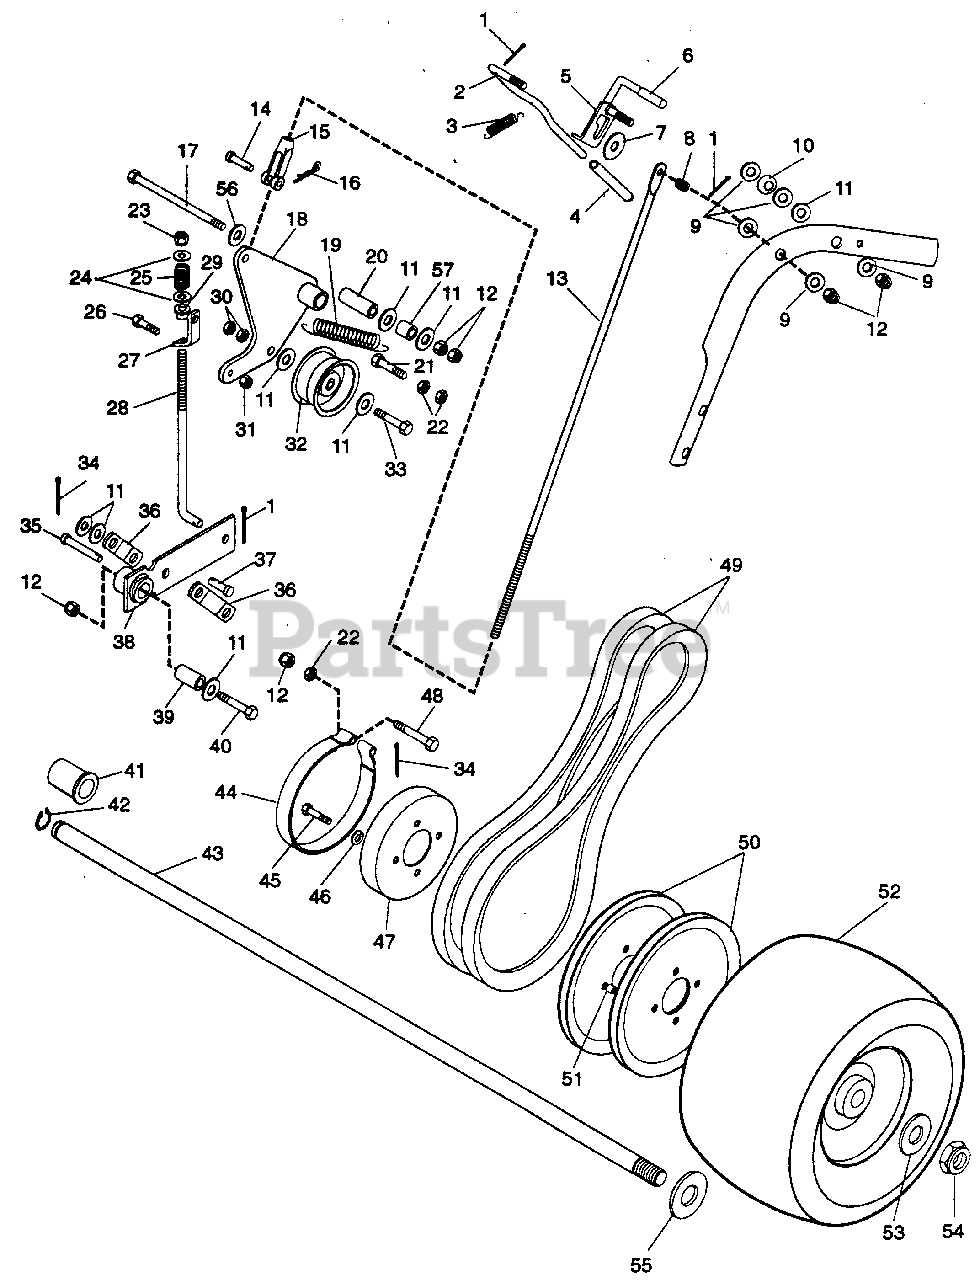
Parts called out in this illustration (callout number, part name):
1	PIN-COTR .09 X .75 PL
2	LVR, HAND CONTROL
3	WLDMT, MWR FRM MULTI-MODE
4	GRIP, HAND CLUTCH LEVER
5	WLDMT, CLUTCH-BRAKE LOCK
6	TIP-BRAKE LOCK LEVER
7	WSHR-FL-STL .438 X 1.375 X .083
8	SG-COMP .045 X .600 X .750 WLD 25
9	WSHR-FL-NY .375 X .75 X .060
10	SPRING WASHER
11	WSHR-FL-STL .406 X .812 X .065 PL
12	NUT-LK-NYL .375-16 PL
13	ROD, CLUTCH ACTUATING
14	PIN-CLEV .372 X 1.25
15	CLVS, 3/8-24 ADJUSTABLE
16	PIN-HAIR INT .08 X .18 X .18
17	BLT-HEX .38-16 X 4.00
18	WLDMT, WHL CLUTCH ARM
19	SG-TENS .069 X .62 X 3.50 WLD 20
20	BUSH., S .385 X .610 X 1.80 ST
21	BLT-HEX .38-16 X 1.50 PL GR 5
22	NUT-HEX .375-16
23	NUT-LK-NYL .312-18 PL
24	WSHR-FL-STL .344 X .688 X .065 PL
25	SG-COMP .125 X .78 X 1.00
26	BLT-HEX .25-20 X .75 PL GR 5
27	L-BKT, PRO BRAKE LINK
28	ROD, BRAKE
29	BSHG-FLG .320 X .620 X .312 NY
30	NUT-LK-CTR .375-16 TYP N
31	NUT-LK-NYL .250-20 PL
32	IDLER 2.75 X 1.25
33	BLT-HEX .38-16 X 2.25 GR 5
34	PIN-COTR .12 X .75 PL
35	PIN CLEV .372 X 1.25
36	LINK, BRAKE ARM
37	PIN-CLEVIS .38 X .594
38	WLDMT, BRAKE ARM
39	BUSH., S .391 X .622 X .950 ST
40	BLT-HEX .38-16 X 2.00 PL GR 5
41	BSHG-FLG 1.010 X 1.38 X 1.4 X 1.65
42	RG-RTNG-EXT .906 X .078
43	AXLE SHAFT, PRO-150
44	ASM, BRAKE BAND, PRO
45	BLT-HEX .31-18 X 1.50 PL GR 5
46	WSHR-LOCK .313 X .078 PL
47	DRUM, BRAKE
48	BLT-HEX .38-16 X 2.00 PL GR 5
49	DRIVE BELT, PRO 150, MTCHD PR
50	PLY-V 9.00 X 3.75
51	BUSH., S. 385 X .625 X .475 ST
52	ASS'Y, WHEEL, 13 X 6.00-6, PRO
53	BRG-R-THRST 1.002 X 1.552 X .030
54	NUT-LK-JAM-NYL .75-1.0 PL
55	WSHR-THRST 1.55 X 1.002 X .093
56	WSHR-FL-STL .390 X .875 X .18 PL
57	BUSHING
